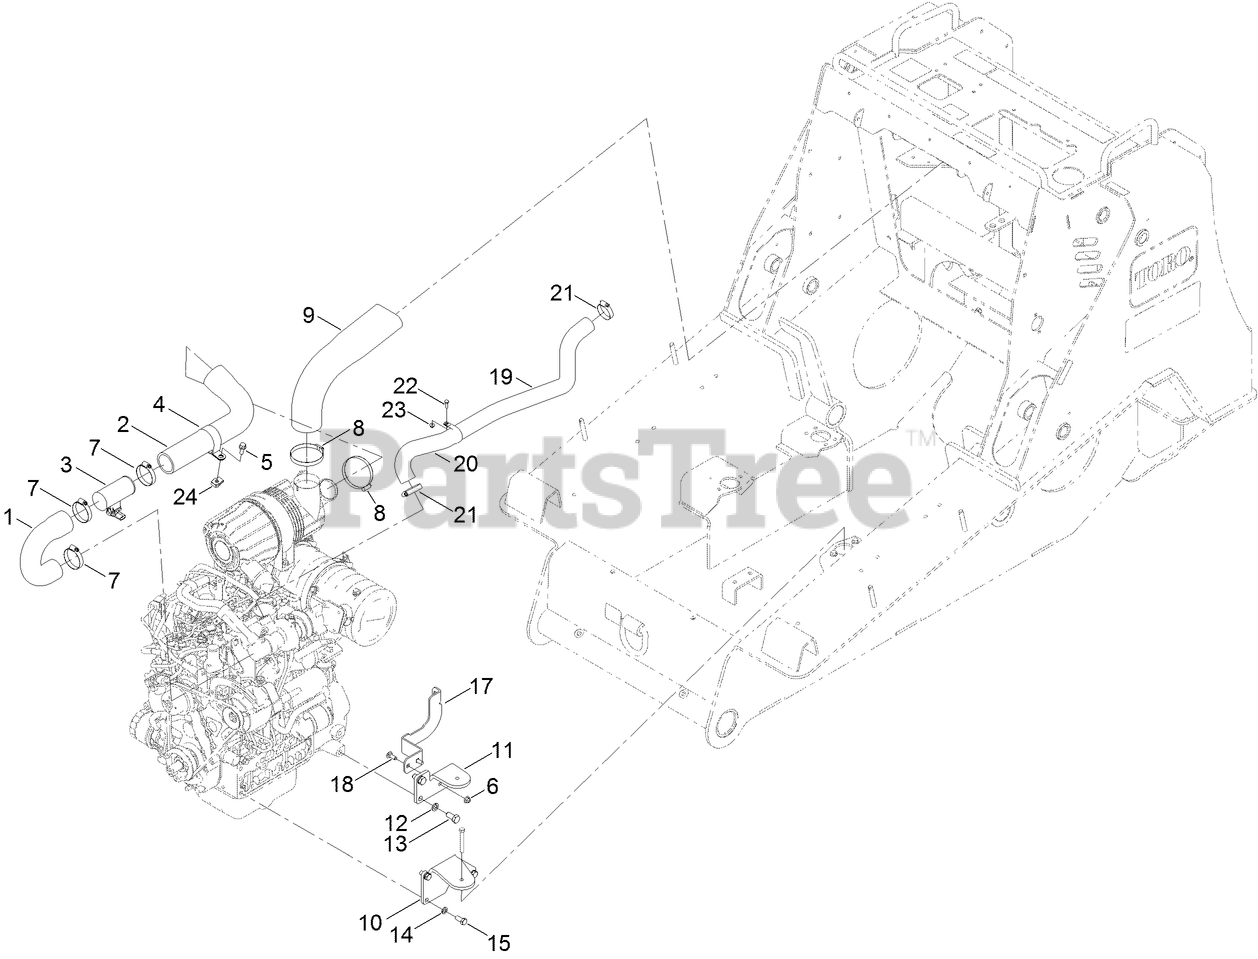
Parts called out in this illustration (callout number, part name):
1	HOSE-INTAKE
2	HOSE-INTAKE, AIR
3	SENSOR
4	CLAMP-R
5	SCREW-HHF
6	NUT-HF, NI
7	CLAMP-HOSE
8	CLAMP-BAND/SCREW
9	HOSE-INTAKE
10	MOUNT-ENGINE
11	MOUNT-ENGINE
12	WASHER-LOCK, SPRING
13	SCREW-HH
14	WASHER-LOCK
15	SCREW-HH
17	BRACKET-PUMP, LH
18	BOLT-CARR
19	HOSE-AIR, COOLER
20	CLAMP-R
21	CLAMP-HOSE
22	SCREW-HH
23	NUT-HF
24	NUT-TINNERMAN
